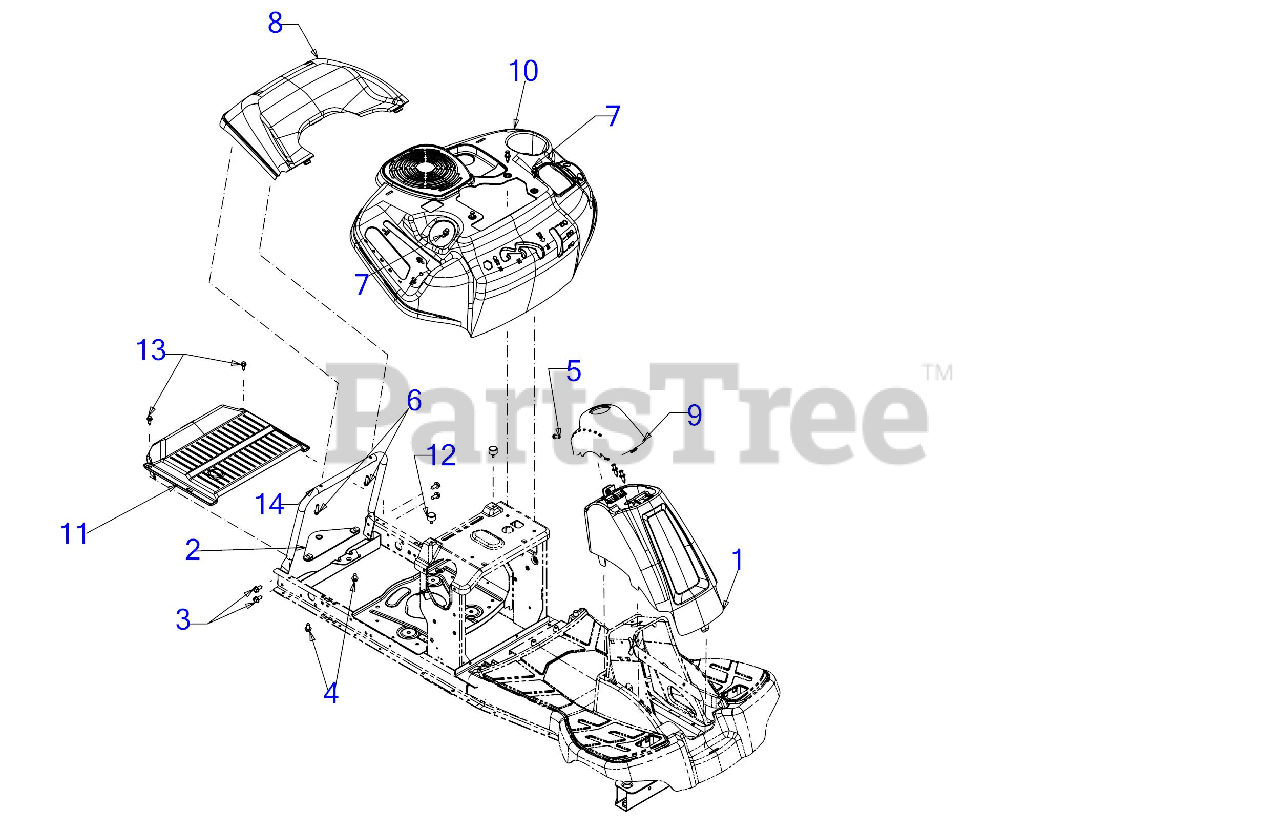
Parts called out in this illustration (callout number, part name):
1	COLUMN COVER ASSEMBLY (MTD RED)
3	SCREW 5/16-18 x .750
4	SCREW 5/16-18 x .625
5	SCREW 1/4-20X.75
6	SCREW 1/4-15 x 1.00
7	PLASTIC RIVET
9	COLUMN STEERING CAP
10	FENDER
11	CVT DRIVE COVER
12	BUMPER .62 DIA x .50
13	SHOULDER SCREW
